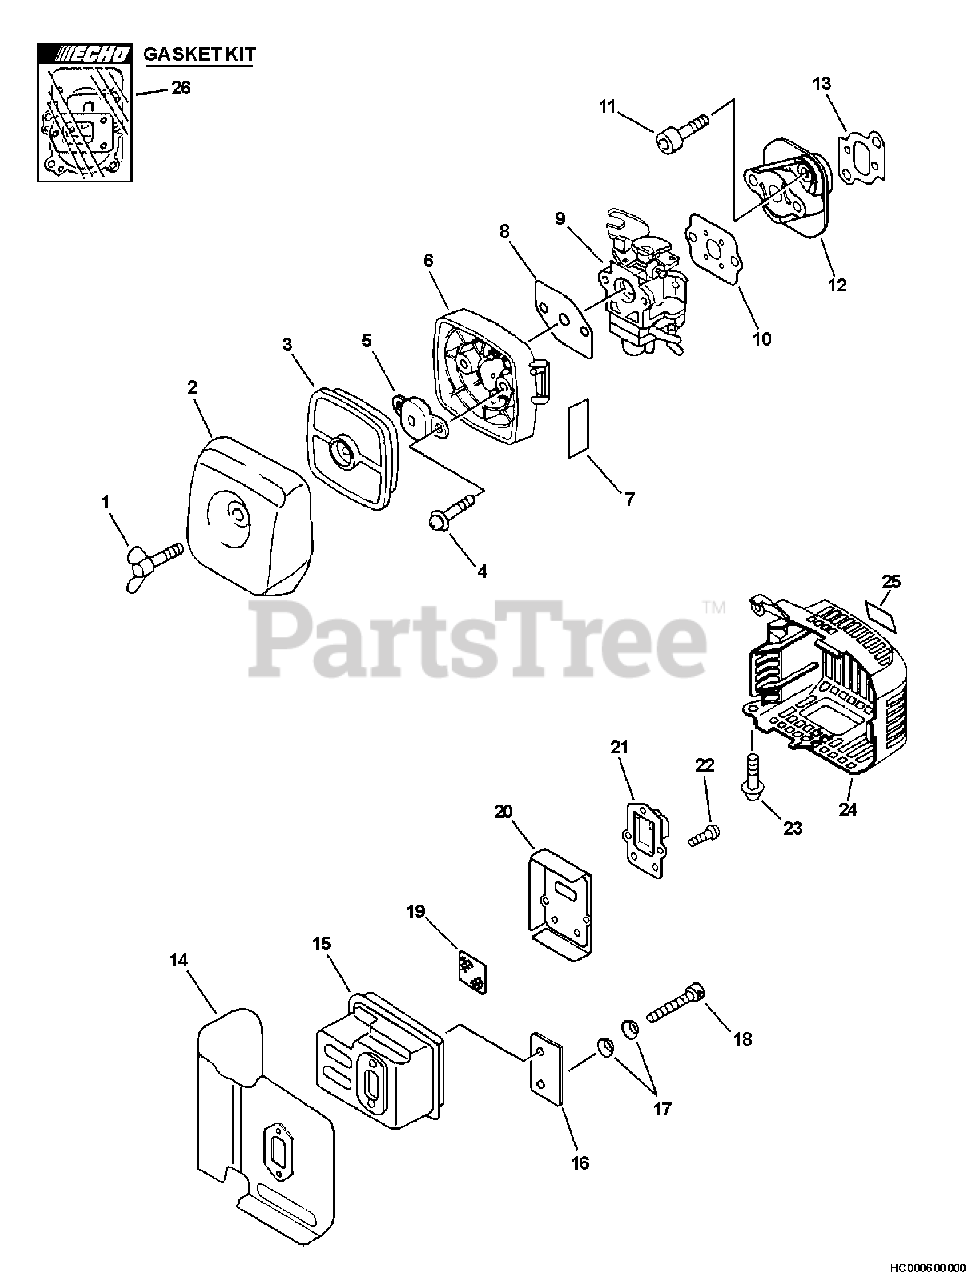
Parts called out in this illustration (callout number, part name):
1	BOLT, WING 5×20
2	COVER, AIR FILTER - GRAY
3	FILTER, AIR - SINGLE LAYER
4	SCREW 5×60
5	PLATE, PREVENT
6	CASE, AIR FILTER - GRAY
7	LABEL, CHOKE
8	GASKET, INTAKE
9	CARBURETOR - WYJ-258
10	GASKET, INTAKE
11	BOLT 5×25
12	INSULATOR, INTAKE
13	GASKET, INTAKE
14	HEAT SHIELD, EXHAUST
15	MUFFLER
16	PLATE, EYE
17	CONICAL WASHER
18	BOLT 5×55
19	SCREEN, SPARK ARRESTER
20	GASKET, EXHAUST
21	GUIDE, EXHAUST
22	SCREW 4×10
23	BOLT 5×12
24	COVER, EXHAUST
25	LABEL, CAUTION - HOT
26	GASKET KIT
